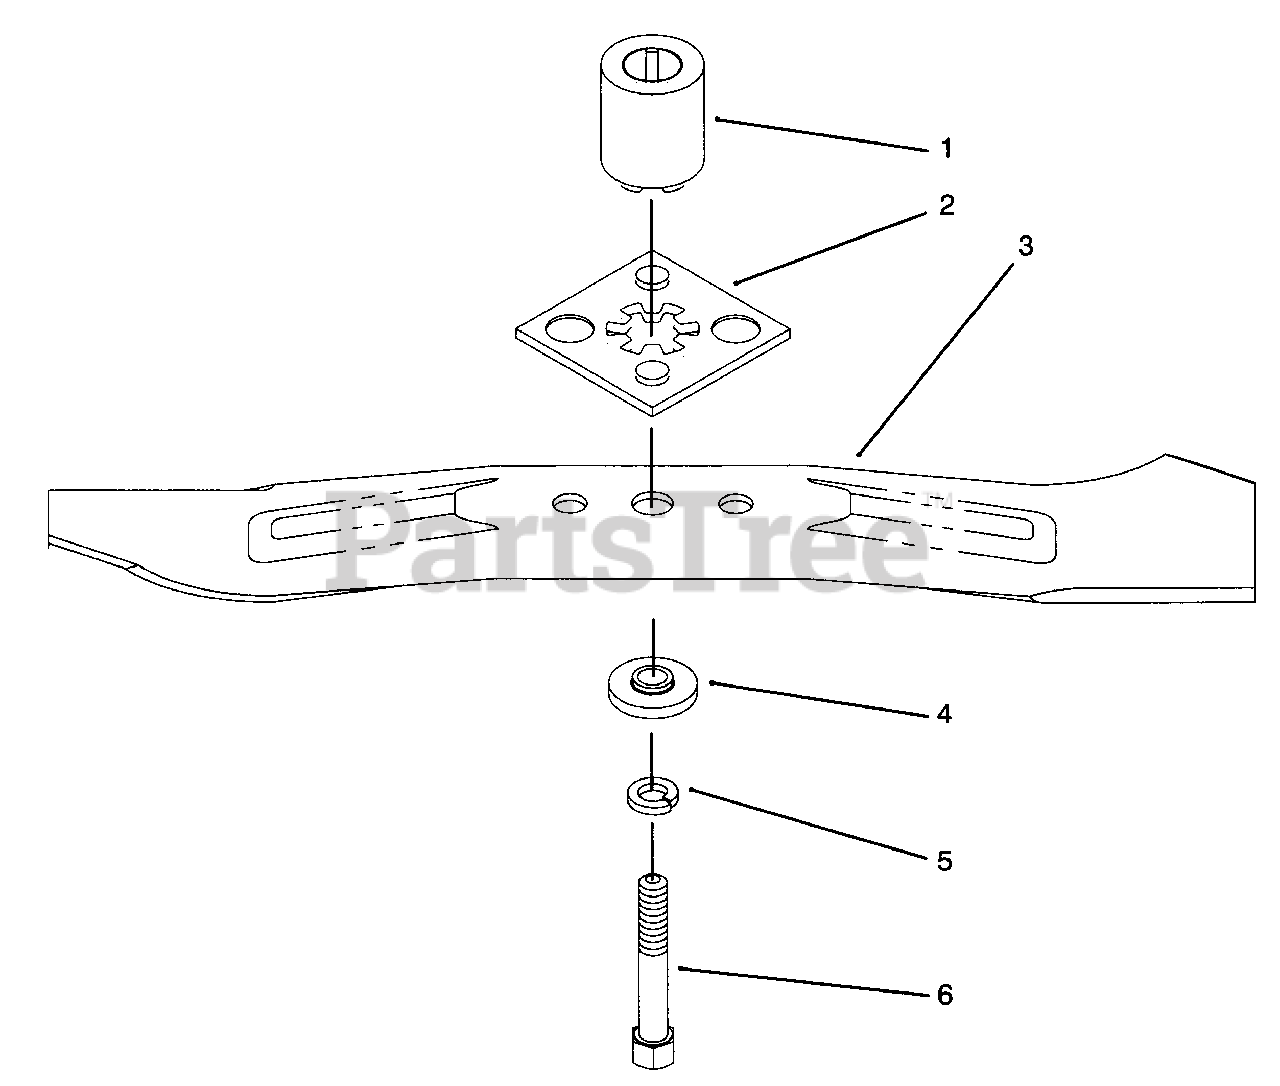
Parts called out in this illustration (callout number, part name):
1	Hub-Blade Driver
2	Plate-Blade Driver
3	Blade-48cm
4	Spacer-Blade
5	Washer-Lock
6	Bolt-Blade
